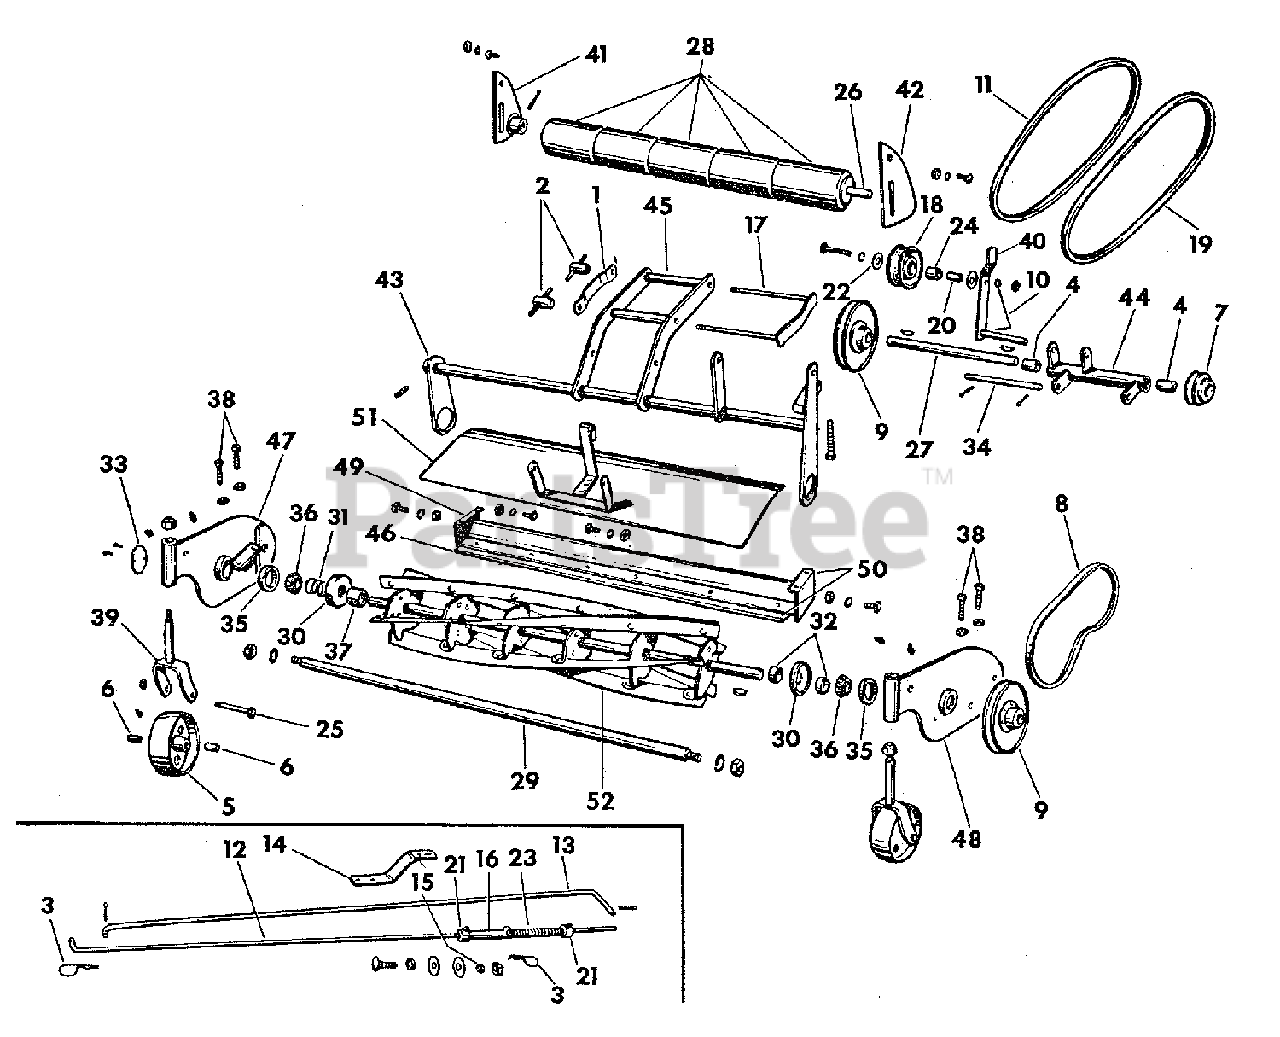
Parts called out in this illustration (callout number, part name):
1	SIDE PLATE, Hitch
2	NUT, Wing, Complete
3	CLIP, Spring
4	BUSHING, Bronze
5	CASTER WHEEL, w/Bearing and Grease Fitting
6	BEARING, Caster Wheel
7	SHEAVE, Reel Driver
8	BELT, Reel Drive, 27" Circumferance
9	COUNTER SHAFT & REEL SHEAVE
10	BELT HOLDER
11	BELT, 31" Circumferance, 1-1/2 HP
12	ROD, Lower Idler
13	ROD, Upper Idler
14	CLUTCH LEVER, Lower
16	SOCKET ASSEMBLY, Rod
17	CLAMP ASSEMBLY, Hitch
18	PULLEY, Idler
19	BELT, 35", 3HP
20	BEARING RACE, Inner
21	COLLAR, Set
22	WASHER, Thrust
23	SPRING, Idler Rod
24	BEARING, Idler Pulley
25	WHEEL SPINDLE, Caster
26	SHAFT, Roller
27	SHAFT, Transmission
28	ROLLER, Hard Wood
29	ROD, Spacer
30	COVER, Bearing
31	SPRING, Bearing
32	SPACER, Bearing, Short
33	CAP, Bearing
34	PIN, Hinge
35	CAP, Bearing
36	CONE, Bearing
37	SPACER, Bearing, Long
38	SCREW, Blade Adjusting
39	FORK ASSEMBLY, Caster
40	LEVER ASSEMBLY, Idler
41	ROLLER BRACKET, R.H.
42	ROLLER BRACKET, L.H.
43	PUSH ARM ASSEMBLY, R.H.
44	BEARING BRACKET, w/Bushings and Grease Fitting
45	PUSH ARM ASSEMBLY, w/L.H. Push Arm
47	LAWN MOWER FRAME ASSEMBLY, R.H.
48	LAWN MOWER FRAME ASSEMBLY, L.H.
49	BAR ASSEMBLY, Cutter
50	CUTTER BAR ASSEMBLY, w/Blade
51	GUARD ASSEMBLY, Grass
52	REEL ASSEMBLY, 24"
